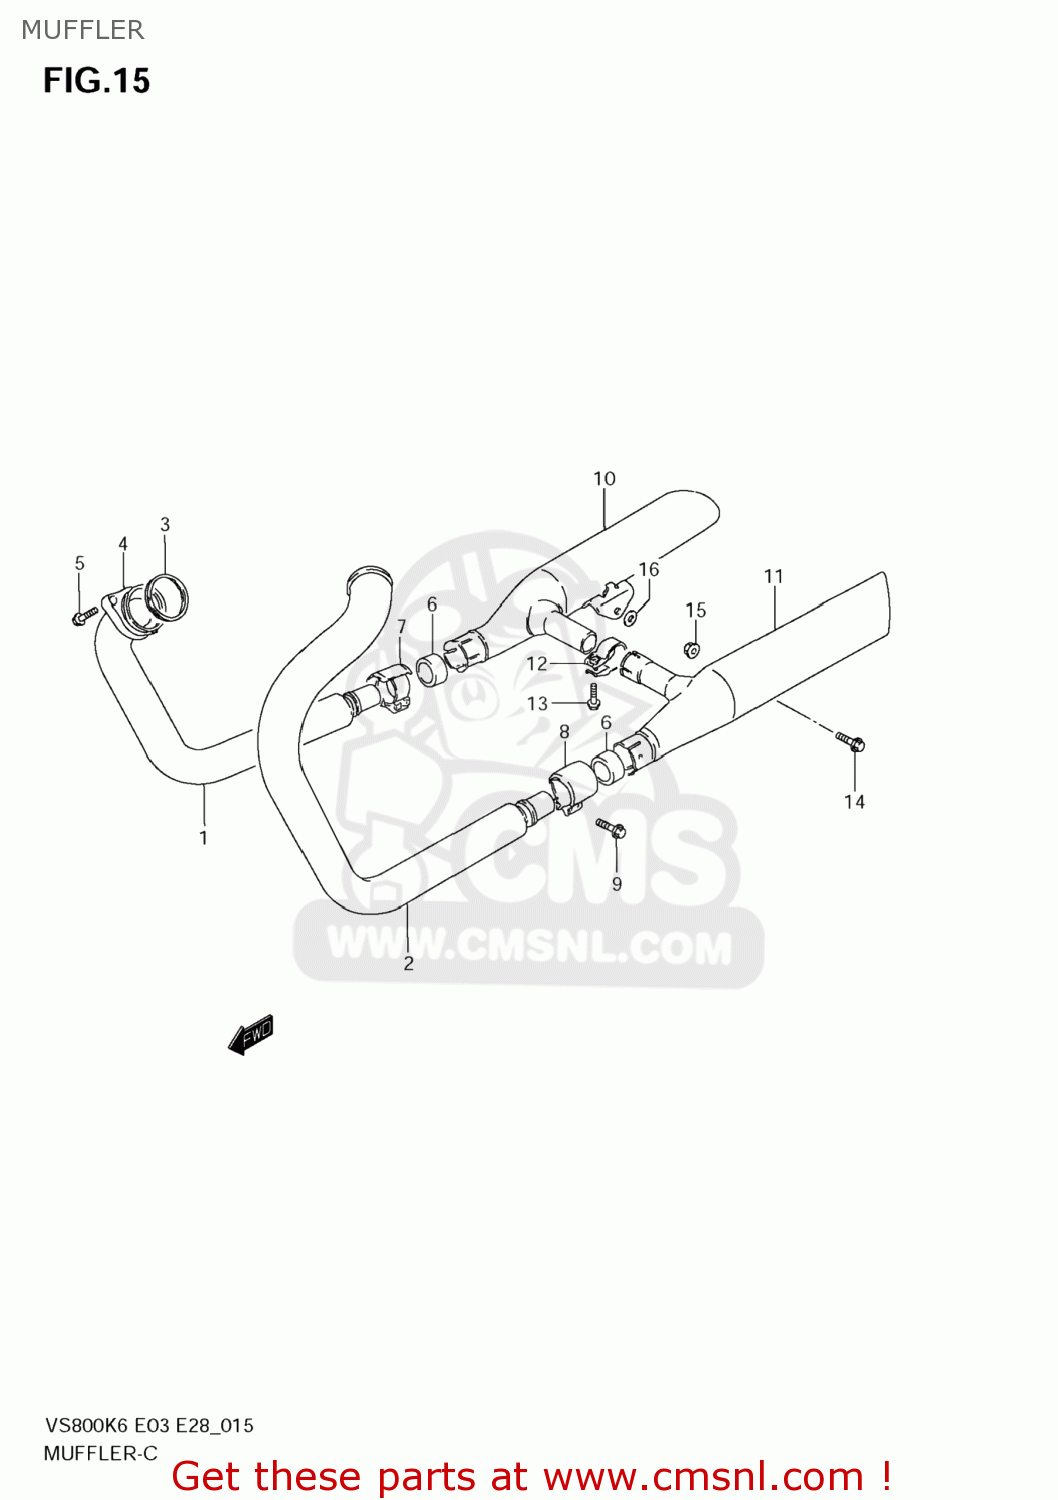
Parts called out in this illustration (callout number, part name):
1	PIPE,EXHAUST,R
2	PIPE,EXHAUST,L
3	GASKET,EXHAUST PIPE (NAS)
4	CLAMP,EXHAUST PIPE
5	BOLT(8X35)
6	CONNECTOR,EXHAUST PIPE
7	CLAMP,MUFFLER CONNECTOR,R
8	CLAMP,MUFFLER CONNECTOR,L
9	BOLT
10	BODY,MUFFLER,R
11	BODY,MUFFLER,L
12	CLAMP,EXHAUST COUPLER
13	BOLT
14	BOLT
15	NUT
16	WASHER(8.5X18X3.20)
